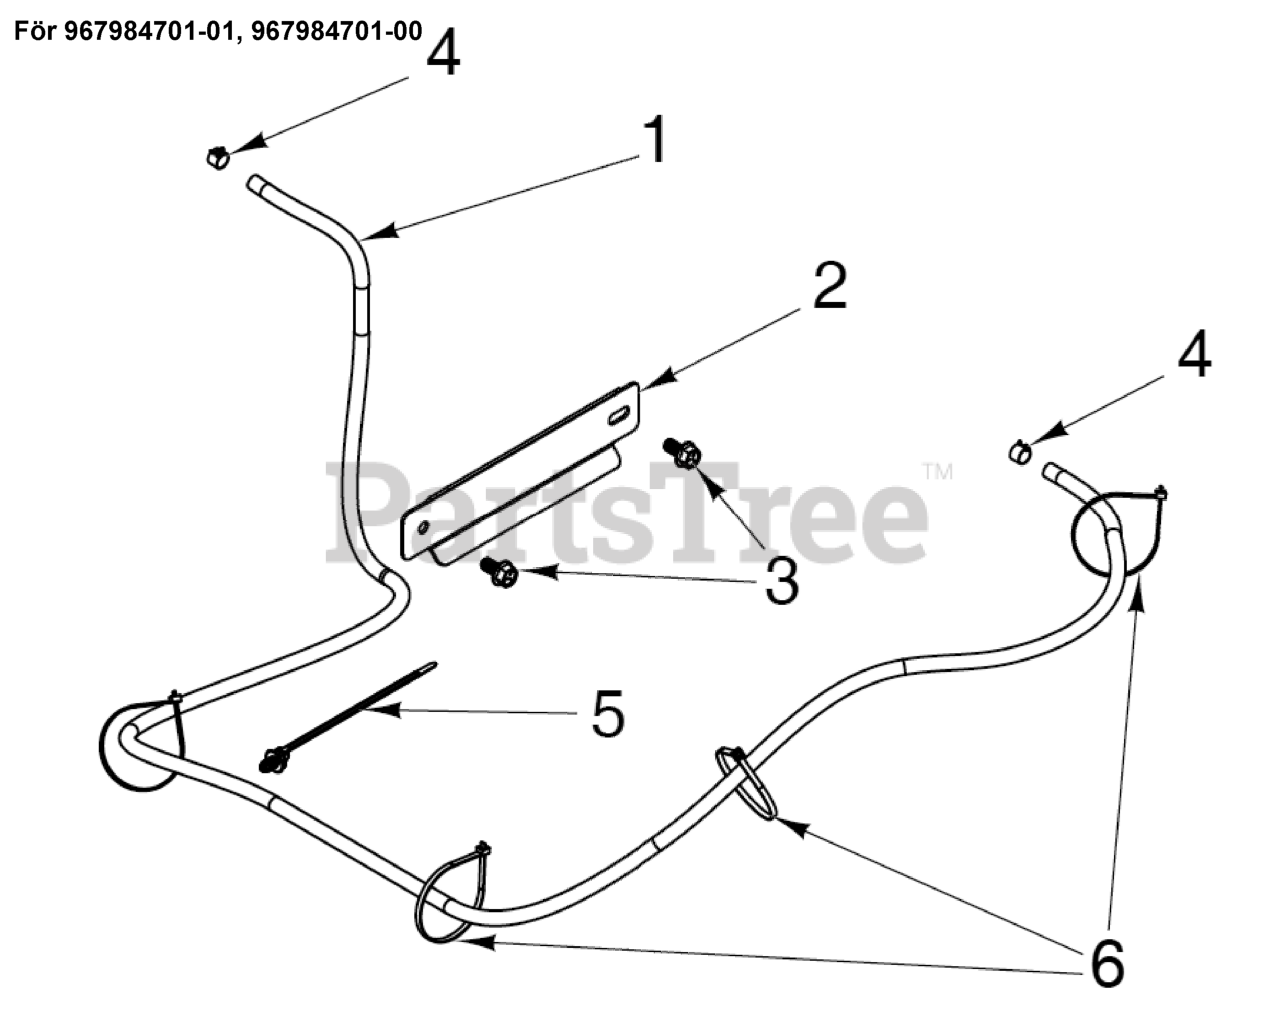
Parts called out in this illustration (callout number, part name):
1	Hoses
2	Plates
3	BOLT.5/16X.625 HEX.W/SHLDR
3	Screws
4	CLAMP, HOSE
5	CABLE.TIE.6".FIRTREE.PZ.REFRES
6	TIE, PLASTIC
